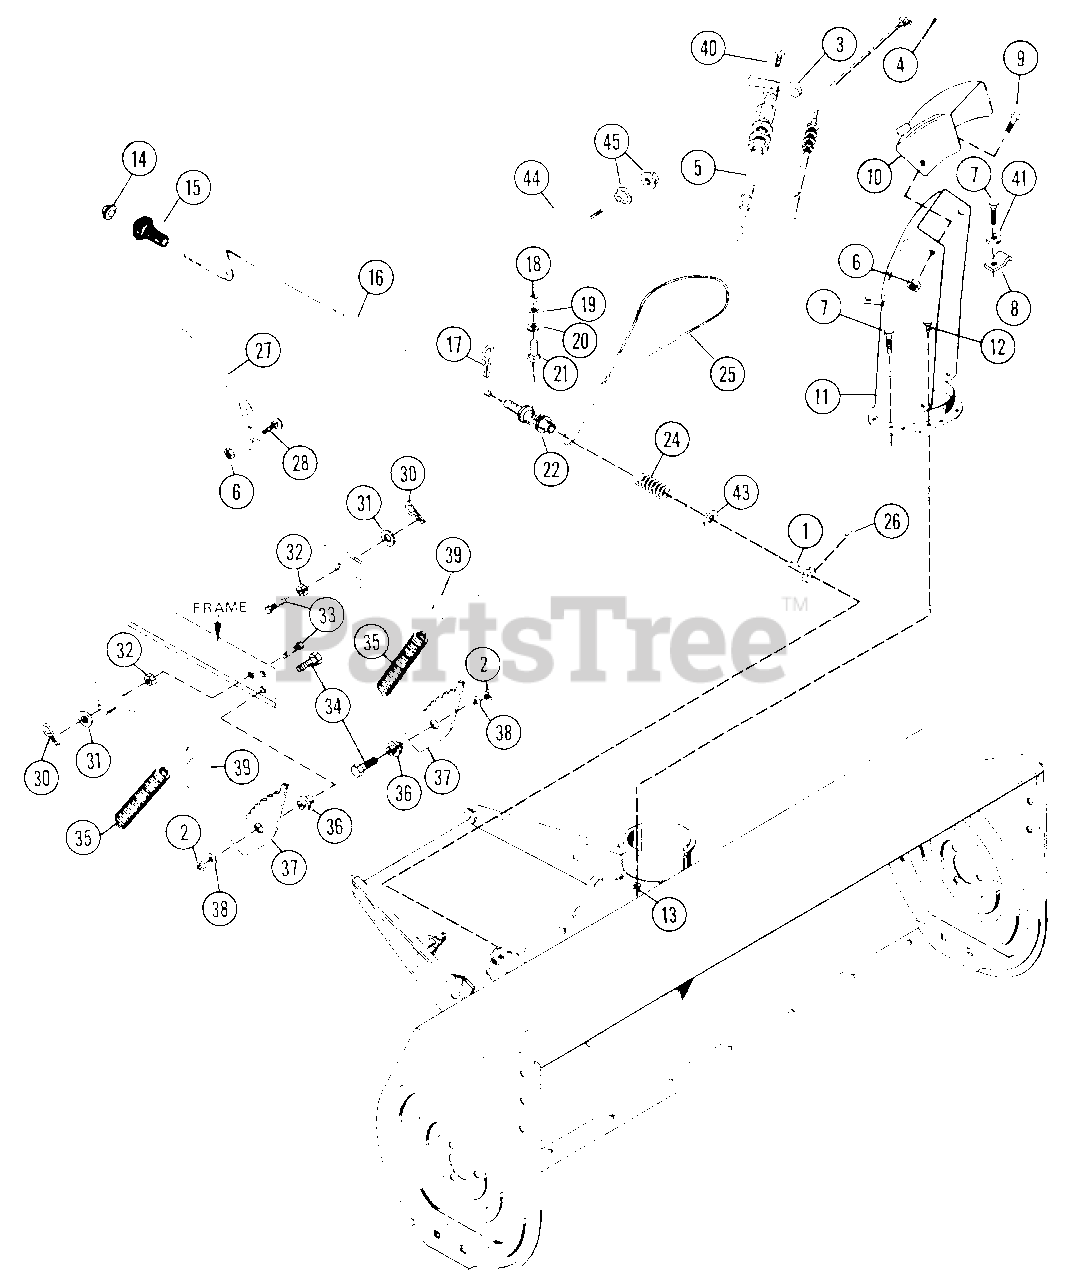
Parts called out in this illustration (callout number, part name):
1	ARM, DISC
2	NUT, LOCK 5/16-18
3	HANDLE, TEE
4	PIN, COTTER .09X.75
5	CABLE, CONTROL
6	NUT, LOCK 3/8-16
7	SCREW, TAPTITE 10-24X.75
8	CLAMP, CABLE
9	BOLT, HEX 3/8-16X.75
10	DEFLECTOR, CHUTE
11	CHUTE, DISCHARGE
12	SCREW, TAPTITE 10-24X.375
13	CLAMP, CHUTE
14	CAP
15	KNOB
16	CRANK, CHUTE CONTROL
17	HAIR PIN, INTERNAL
18	NUT, HEX 1/4-20
19	WASHER, LOCK 5/16 REG.
20	WASHER, FLAT .281X.625X.065
21	BOLT, 1/4-20X.625 RD HD SQ NK
22	SPOOL
24	SPRING, COMPRESSION
25	CABLE
26	PIN, SPRING .187X1.000
27	SUPPORT
28	BOLT, 3/8-16X1.00 RD HD SQ NK
30	HAIRPIN, INTERNAL 3/32
31	WASHER, FLAT .56X1.87X.109
32	NUT, LOCK 1/2-13
33	STUD, WEIGHT
34	BOLT, HEX 5/16-18X1.25
35	SPRING, EXTENSION
36	SPACER
37	SPRING ASSIST CONTROL
38	WASHER, FLAT .406X.812X.065
39	ARM, SPRING
40	SCREW, MACHINE 10-32X.50
41	WASHER, FLAT .219X.438X.049
43	WASHER, .635/.645X1.005X.062
44	CABLE SUPPORT
45	NUT, LOCK 1/4-20
NS	DECAL, DANGER HAND
NS	DECAL, CHUTE CRANK
NS	DECAL, CAUTION
